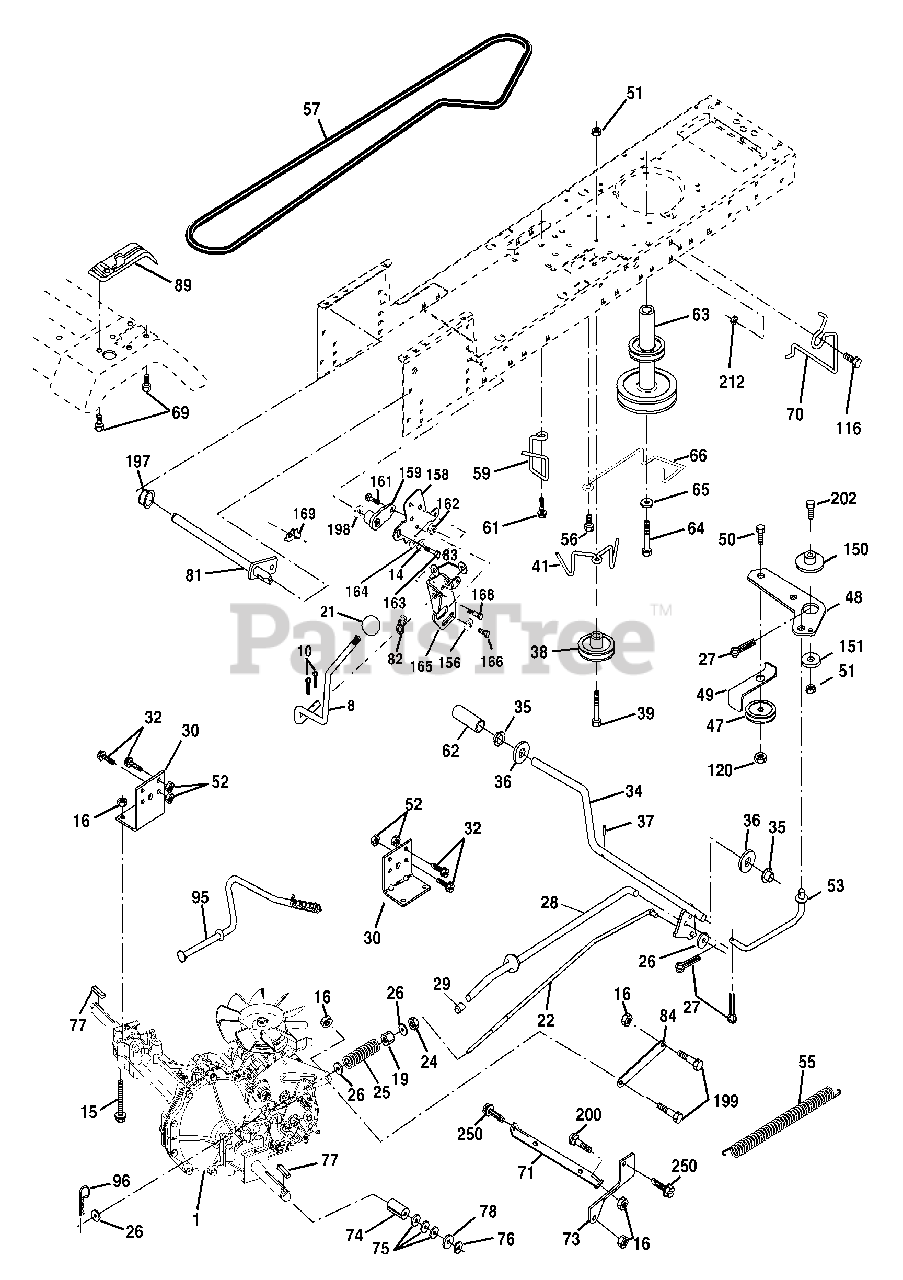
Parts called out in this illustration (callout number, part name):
8	Rod Shift Hydro LT
10	Pin Cotter 1/8 x 1 CAD
14	Washer Lock Hvy Helical
15	Bolt, Hex FLGHD 5/16-18 Gr. 5
16	Nut Lock Hex W/Ins 5/16-18unc P
19	Nut Lock Hex W/Wsh 3/8-16 Unc
21	Knob, Round 1/2-13
22	Rod, Brake Hydro
24	Nut
25	Spring, Brake Rod
26	Washer
27	Pin Cotter 1/8 x 3/4 CAD.
28	Rod, Parking Brake
29	Cap, Parking Brake
30	Bracket, Transaxle
32	Bolt Hex Hd 5/16-18 Unc x 3/4
34	Shaft, Foot Pedal
35	Bearing, Nylon
36	Washer
37	Pin, Roll
38	Pulley, Flat Composite
39	Bolt Fin Hex 3/8-16 x 3
41	Keeper, Belt Idler
47	Pulley, Idler, V-Groove
48	Bellcrank Clutch Grnd Drv STL
49	Retainer, Belt
50	Bolt Carr. SH 3/8-16 x 1-1/2 Gr. 5
51	Nut Crownlock 3/8-16 UNC
52	Nut Crownlock 5/16-18 UNC
53	Link, Clutch
55	Spring, Return, Clutch
56	Screw 3/8-16 x 1-1/4
57	V-Belt, Ground Drive
59	Keeper, Center Span
61	Screw 3/8-16 x .875
62	Cover, Pedal
63	Pulley, Engine
64	Bolt, Hex
65	Washer
66	Keeper Belt Engine
69	Screw
70	Guide Belt
71	Strap Torque Lh Hydro
73	Strap Torque Rh Hydro
74	Spacer, Axle
75	Washer 25/32 x 1-1/4 x 16 Gauge
76	E-Ring
77	Key, Square
78	Washer 25/32 x 1-5/8 x 16 Gauge
81	Shaft Asm. Cross Hydro
82	Spring Torsion T/A
83	Washer 17/32 x 3/4 x 16 Ga.
84	Link Transaxle
89	Console, Hydro
95	Control Asm Bypass Hydro
96	Retainer Spring 1" Zinc/Cad
116	Bolt Rdhd Sq Neck 3/8-16 x 1
120	Nut Lock Flg 3/8-16
150	Spacer Retainer
151	Washer 13/32 x 2 x 10 Ga.
156	Washer Srrted 5/16 ID x 1.125
158	Bracket Shift Mount
159	Hub Tapered Flange Shift Lt
161	Bolt Rdhd Sqnk 1/4-20 x 3/4 Gr 5
162	Nut Crownlock 1/4-20 Unc
163	Bolt Hex Fin 1/4-20 Unc x 1 Gr 5
164	Washer 5/8 x .281 x 10 Ga
165	Bracket Pivot Lever
166	Screw 5/16-18 x 5/8
168	Bolt Shoulder 5/16-18 x .561
169	Plate Fastening Lt
197	Nyliner Snap-In 5/8" ID
198	Washer Nyl 7/8 ID x .105
199	Bolt Shoulder 5/16-18 Unc
200	Bolt Rdhd Sqnk 5/16-18 Unc x 1
202	Bolt RDHD 3/8-16 x 1-3/4 Gr 5
212	Nut Hex Flg Lock
250	Screw Thdrol. 3/8-16 x .75
